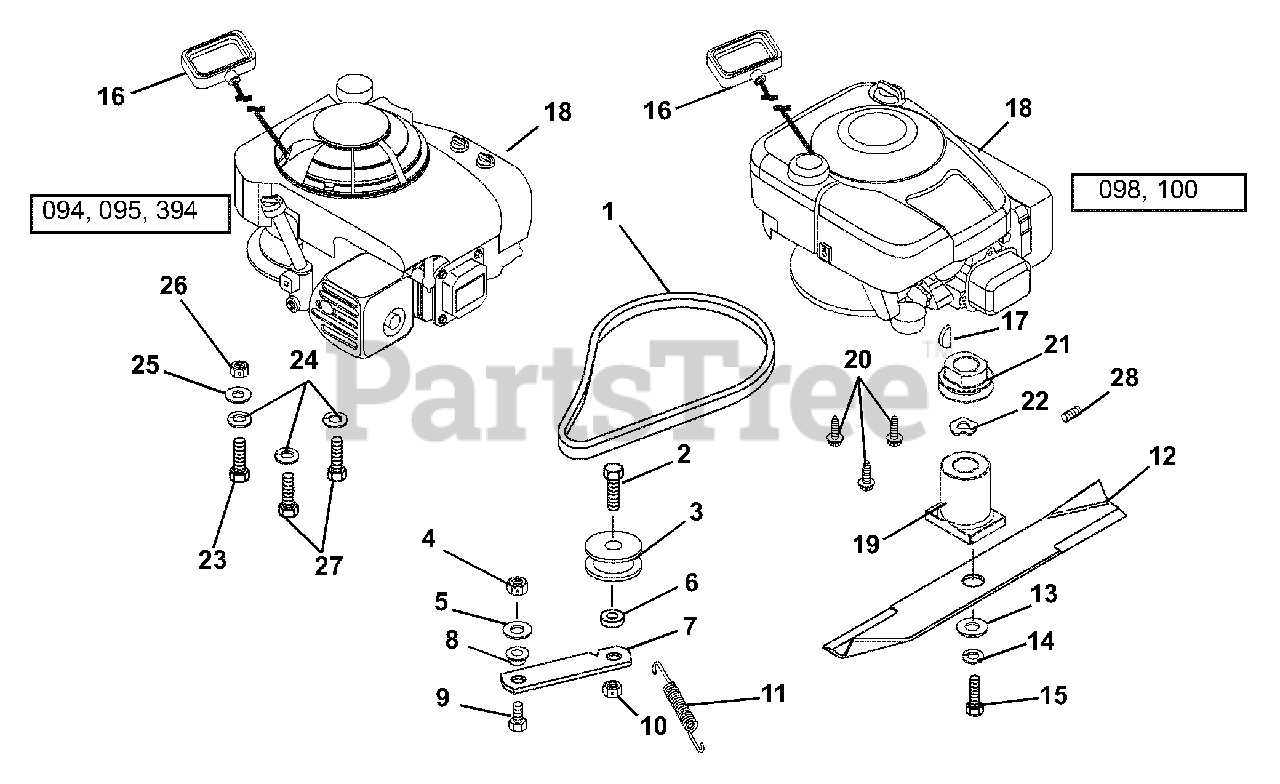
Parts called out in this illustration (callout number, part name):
1	V-Belt 3L Section (094, 098, 100, 394)
2	Bolt, Hex .44-14 x 1.50 Grade 5 (094, 098, 100, 394)
3	Idler, Flat 1.75 x .47 (094, 098, 100, 394)
4	Nut, Locking Center .31 -18 (094, 098, 100, 394)
5	Washer, Flat Steel .344 x .688 x .065 (094, 098, 100, 394)
6	Bushing, Sleeve .47 x .75 x .43 (094, 098, 100, 394)
7	Idler Arm (094, 098, 100, 394)
8	Bushing, Flange .325 x .50 x .25 x 1.12 (094, 098, 100, 394)
9	Bolt, Hex .31-18 x .75 Grade 5 (094, 098, 100, 394)
10	Nut, Locking Center .44-14 (094, 098, 100, 394)
11	Spring, Tension .043 x .44 x 3.31 (094, 098, 100, 394)
12	Blade, 21" Mower
12	Blade, 21" Mower Tungsten
13	Washer, Flat Steel .390 x 1.50 x .125
14	Washer, Locking .38 x .094
15	Bolt, Hex .38-24 x 2.00 Grade 8
16	Recoil Start Handle
17	Key, Woodruff .156 x .625 x .25 SAE #6
18	Engine, Briggs and Stratton 6.75HP Intek OHV (098, 100)
18	Engine, Honda 5.5 HP OHV (094, 095, 394)
19	Blade Adapter (098, 100)
19	Adapter, Blade Hub (094, 095, 394)
20	Screw, Tapping .38-16 x 1.00 Hex Washer Head (098, 100)
21	Pulley (098, 100)
21	Pulley, Steel Drive (094, 394)
22	Washer, Wave .885 x 1.31 x .125 (098, 100)
23	Bolt, Hex .31-24 x 1.50 Grade 5 (094, 095, 394)
24	Washer, Locking .31 x .078 Regular (094, 095, 394)
25	Washer, Flat Steel .344 x .688 x .065 (094, 095, 394)
26	Nut, Hex .312-24 (094, 095, 394)
27	Bolt Hex .31-24 x 1.00 Grade 5 (094, 095, 394)
28	Screw, Set .31-18 x .38 Socket Head (094, 394)
